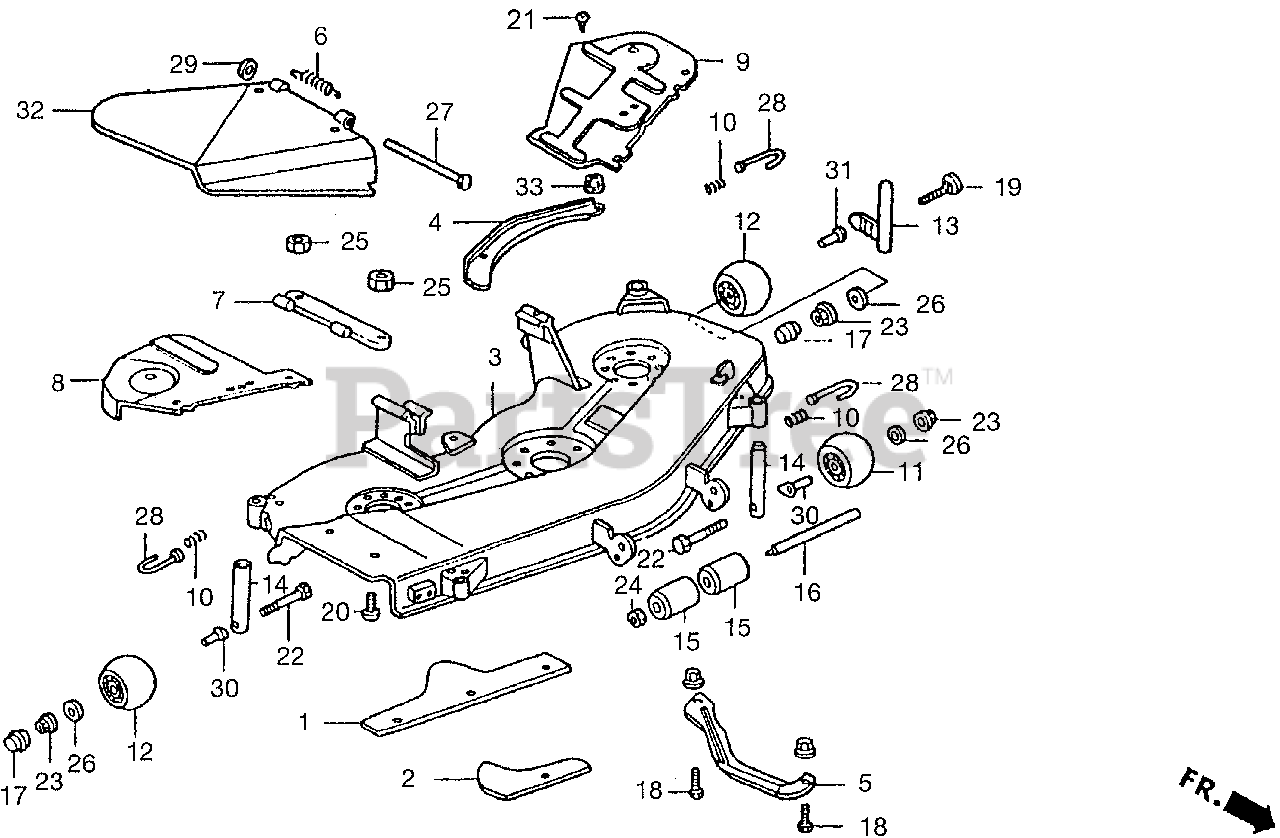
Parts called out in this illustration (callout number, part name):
1	BAFFLE, R. FR.
2	BAFFLE, L. FR.
3	HOUSING, CUTTER
4	PLATE, RR. HOUSING
5	GUARD, HOUSING
6	SPRING, DISCHARGE
7	HINGE, DISCHARGE
8	COVER, R. BELT
9	COVER, L. BELT
10	SPRING, RELEASE
11	ROLLER, ANTI-SCALP
12	ROLLER, GAUGE
13	SHAFT, GAUGE ROLLER
14	SHAFT, ANTI-SCALP
15	ROLLER, CENTER
16	SHAFT, ROLLER
18	BOLT, CARRIAGE (8X16)
19	BOLT, CARRIAGE (8X70)
20	BOLT, CARRIAGE (8X20)
21	SCREW, DECK COVER
22	BOLT, HEX. (8X90)
23	NUT, FLANGE (8MM)
24	NUT, LOCK (10MM)
25	NUT B, LOCK (8MM)
26	WASHER, SPECIAL HARDENED
27	PIN, CHUTE GUARD
28	PIN, GAUGE WHEEL
29	RETAINER, FRAME
30	BUSHING, FLANGED
31	BUSHING, CUTTER DECK
32	ADAPTER, DISCHARGE (NA USE ALT:06814-V09-D01)
33	NUT D, LOCK (8MM)
